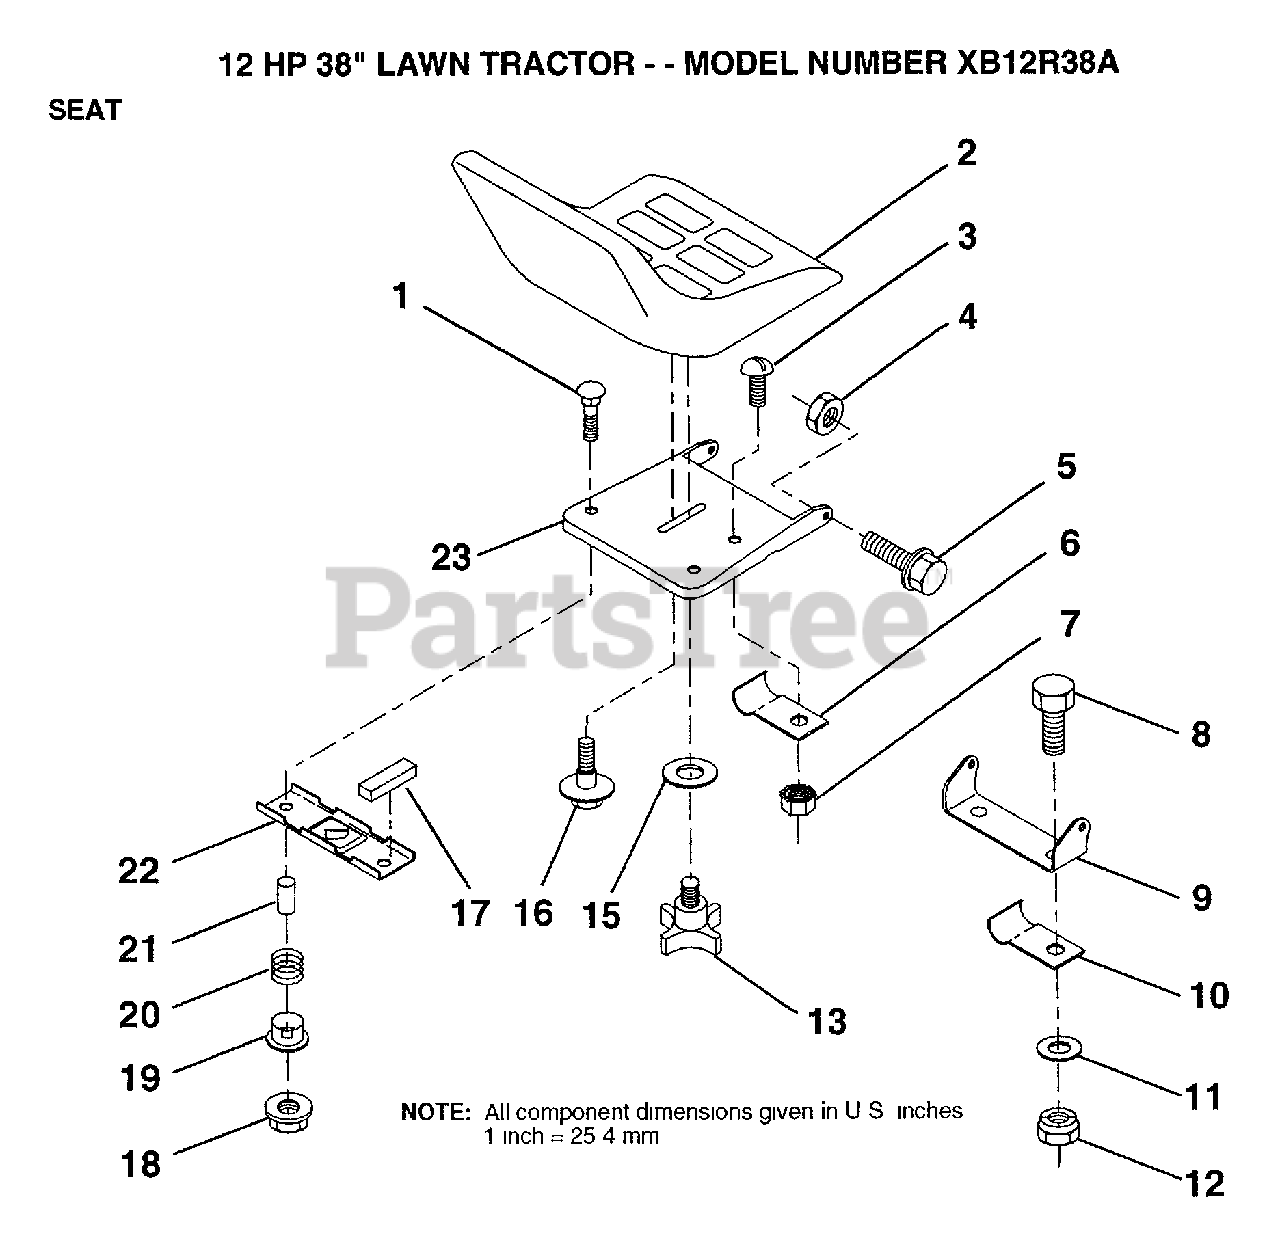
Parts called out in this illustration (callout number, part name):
7	"NUT,KEPS"
10	"CLIP,INSULATOR"
11	WASHER
13	"KNOB 1/2"" YT"
15	WASHER
16	"BOLT,SHOULDER"
17	STRIP FORM
19	BUSHING
20	SPRING
21	SPACER SPLIT
22	BRKT SWITCH
